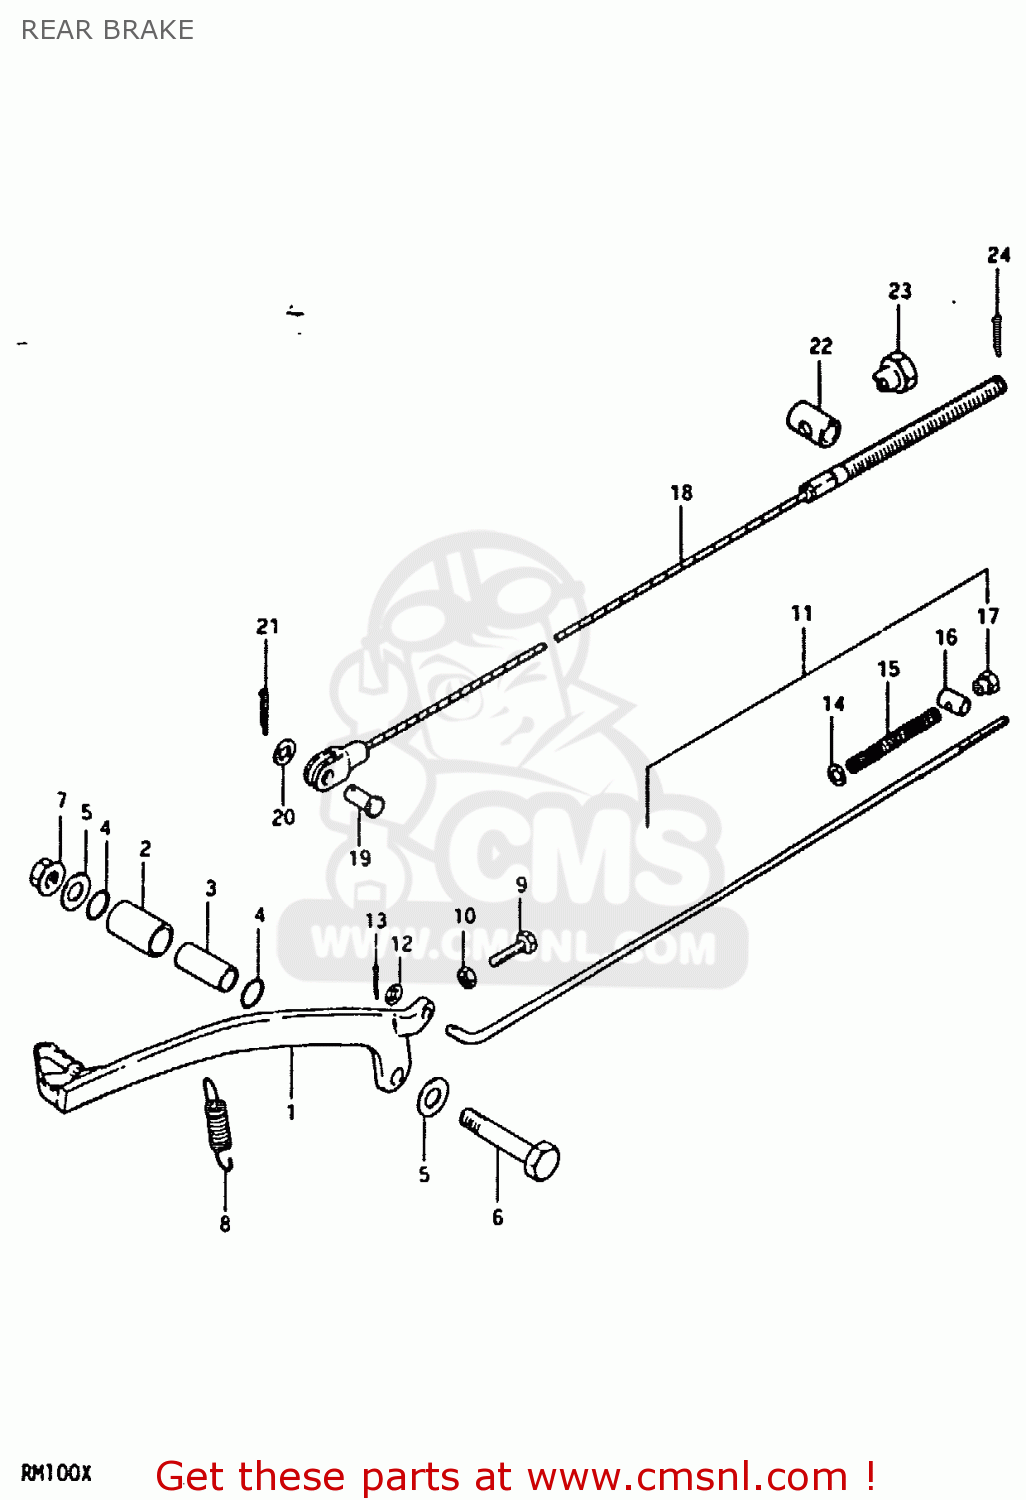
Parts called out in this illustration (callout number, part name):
1	PEDAL,BRAKE
2	BUSH
3	SPACER(10X14X32.2)
4	O RING(D:1.5,ID:13.8)
5	WASHER
6	BOLT
7	NUT
8	SPRING
9	BOLT(6X23)
10	NUT
11	ROD ASSEMBLY,REAR BRAKE
12	WASHER
13	PIN 20X20
14	WASHER
15	SPRING
16	PIN
17	NUT
18	CABLE,RR BRAKE
19	PIN(L:17.5)
20	WASHER
21	PIN 20X20
22	PIN
23	NUT
24	PIN
